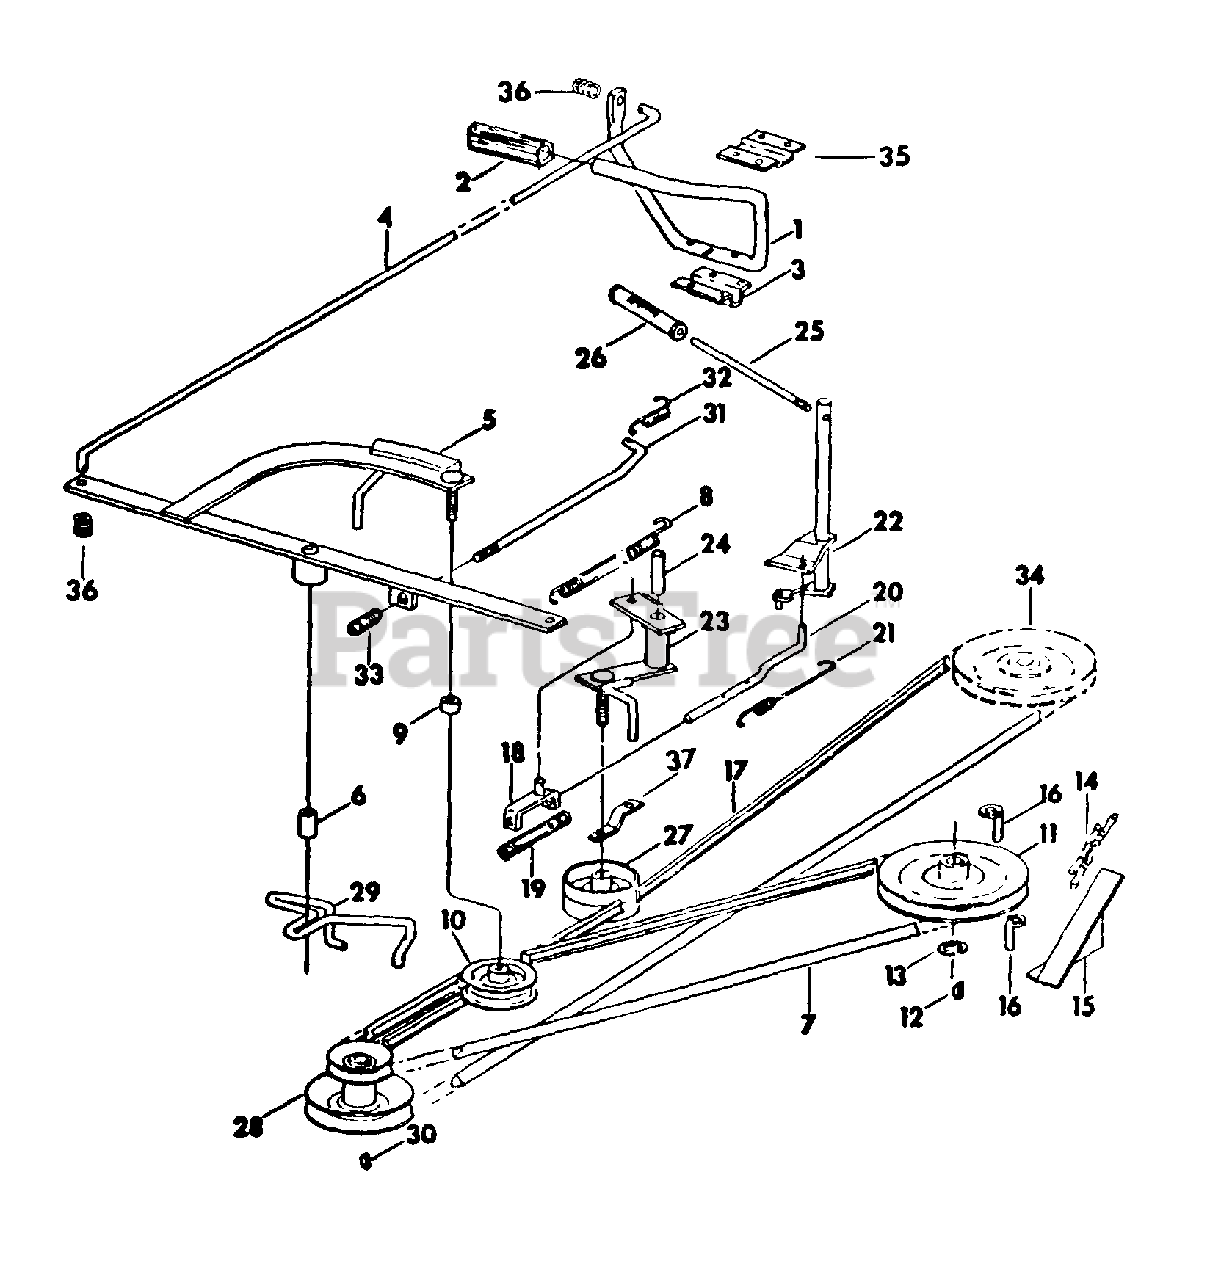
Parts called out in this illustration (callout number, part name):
1	PEDAL, CLUTCH AND BRAKE
3	CLAMP, PEDAL PIVOT
4	ROD, CLUTCH CONTROL
5	ARM ASSY, SHIFTER PIVOT
6	BUSHING, SHIFTER ARM
7	BELT, FORWARD DRIVE
8	SPRING, PEDAL RETURN
9	SPACER, 3/8 X .938 EXTRA STRONG PIPE
10	IDLER, BALL BRG
11	PULLEY, TRANSMISSION DRIVE
12	KEY, 3/16 X 3/4 WOODRUFF 9
13	RING, 579 EXT RET
14	CHAIN, FINAL REDUCTION
15	SHIELD ASSY, DRIVE CHAIN
16	GUIDE, BELT
17	BELT, MOWER DRIVE
18	STRAP ASSY, IPTO
19	SPRING, IPTO
20	ROD, MOWER SHIFTER
21	SPRING, IPTO RETURN
22	LEVER ASSY, MOWER SHIFTER
23	LEVER ASSY, SHIFTER ARM
24	BUSHING, IPTO
25	ROD, SHIFTER HANDLE
26	GRIP, SHIFTER HANDLE
27	PULLEY, MOWER SHIFTER IDLER
28	PULLEY, ENGINE AND MOWER DRIVE
29	GUIDE, BELT PTO AND FORWARD DRIVE
30	KEY, 5/32 X 5/8 WOODRUFF 6
32	SPRING, BRAKE RETURN
33	SPRING, COMPRESSION
34	PULLEY, CENTER
35	SPRING, CLUTCH PEDAL
36	SPRING, ANTI-RATTLE
37	RETAINER, MOWER BOLT
